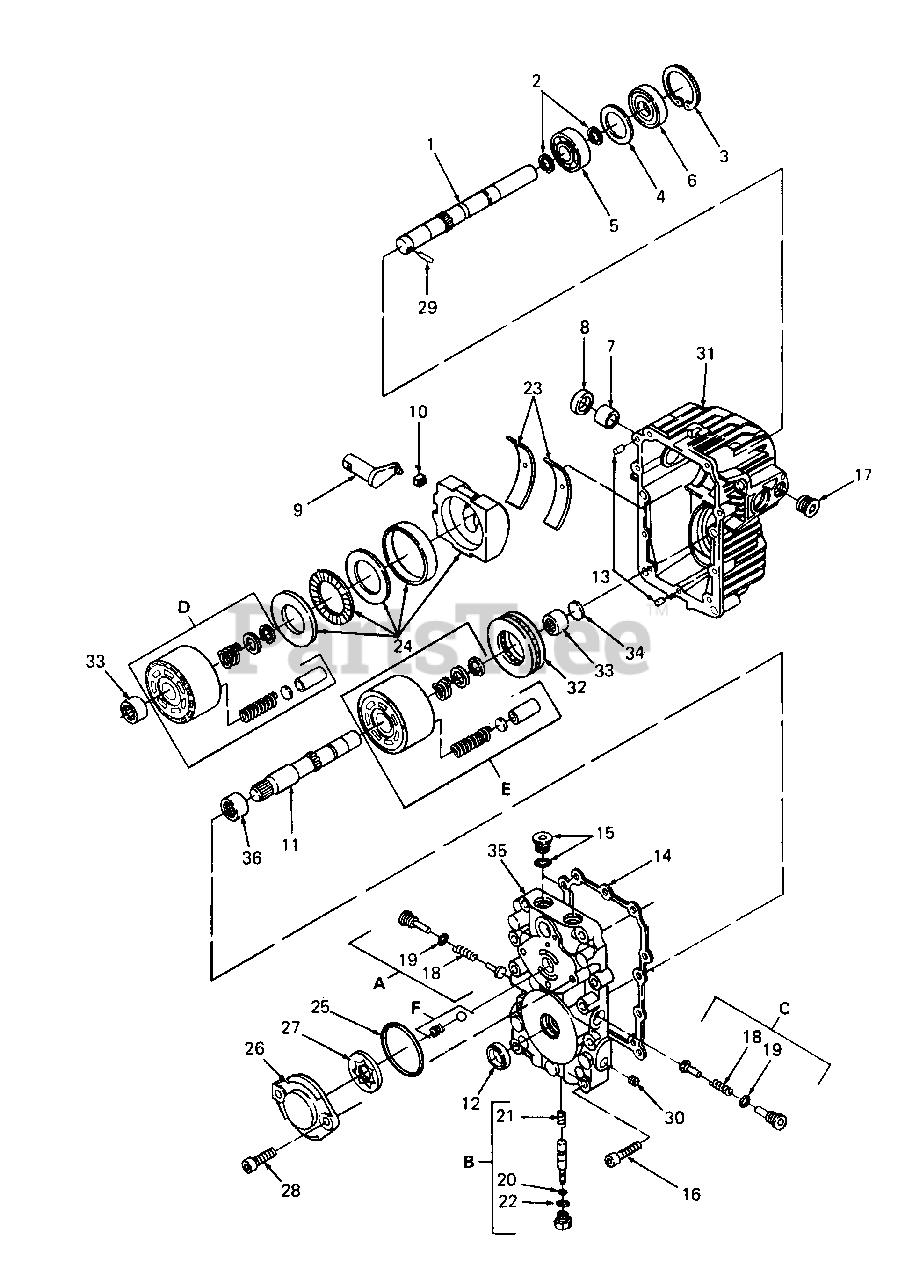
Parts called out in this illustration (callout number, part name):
1	Shaft, Pump
2	Ring, Retaining
3	Ring, Retaining
4	Spacer
5	Bearing, Ball
6	Seal, Lip
7	Bearing, Journal
8	Seal, Lip
9	Arm, Trunnion
10	Guide, Slot
11	Shaft, Motor
14	Gasket, Center Section
19	O-Ring
20	O-Ring
21	Spring
22	O-Ring
23	Bearing, Cradle
26	Housing, Charge Pump
27	Gerotor Assy
31	Housing Assy
32	Bearing, Thrust Ball
33	Bearing, Needle
34	Washer, Thrust
35	Center Section Assy
36	Bearing, Needle
A	Kit, Poppet Check Valve
B	Kit, Bypass Valve
C	Kit, Orificed Check Valve
D	Kit, Pump Cylinder Block
E	Kit, Motor Cylinder Rock
F	Kit, Charge Relief Valve
